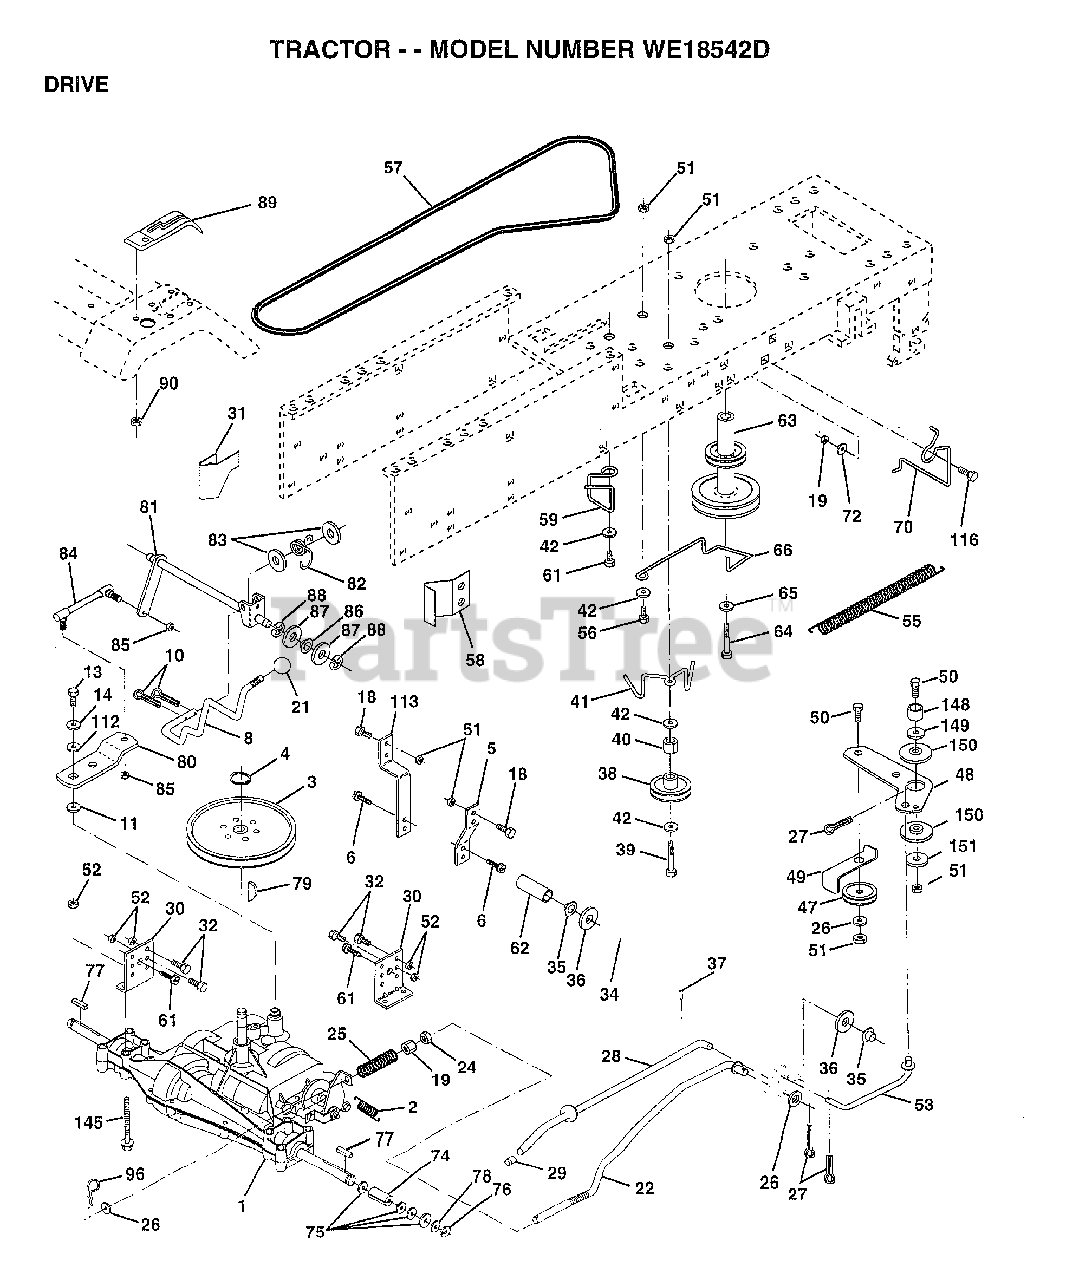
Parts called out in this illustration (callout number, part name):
2	SPRING.BRAKE.RETU
3	PULLEY TRANS
5	STRAP TORQUE
6	SCREW
8	ROD SHIFT FEND LT
10	PIN COTTER 1/8
11	WASH-SHFT PLT LT
13	BOLT.1/4-28.W/PAT
14	LOCKWASHER
18	BOLT
19	NUT
21	KNOB T (1/2-HOLE)
22	BRAKE ROD
24	NUT
25	SPRING ROD LT
26	WASHER
27	COTTER PIN
28	ROD.BRAKE.PARK.LT
29	PLUNGER CAP T
30	TRANSAXLE MTG BKT
31	"KEEPER,BELT LH T"
32	BOLT
34	SHAFT ASM-PEDAL F
35	NYLON BEARING
36	WASHER LT
38	FLAT IDLER PULLEY
39	BOLT
40	SPACER T
41	"KEEPER,BELT.IDLER FLAT"
42	WASHER
48	BELLCRANK.CLUTCH
49	RETAIN BELT
53	"LINK, CLUTCH T"
55	"SPRING, RETURN LT"
58	"KEEPER,BELT RH T"
59	KEEPER BELT CNTSP
61	SCREW
62	PEDAL COVER T
63	PULLEY.ENGINE
64	BOLT
65	LOCKWASHER
66	KEEPER-BELT
70	KEEPER BELT ENG
72	WASHER
74	SPACER AXLE
75	WASHER
76	E-RING LT
77	SQUARE KEY
78	WASHER
80	"ARM.SHIFT.20""TIRE"
81	SHAFT ASM CROSS
82	"SPRING,TORSION"
83	WASHER
84	"ROD.TIE.20""P930LT"
85	NUT.CNT.LOCK.1/4
86	BUSHING
87	WASHER D
88	KLIP RING
89	CONSOLE.SHIFT.LT.5SP.GREY
90	NUT
96	RETAINER M
112	WASHER LT
113	"STRAP,TORQUE"
116	BOLT RDHD 3/8-16
145	BOLT.HEX.FLGHD
149	SPACER RETAINER
150	BUSHING.NYLON
151	WASHER
